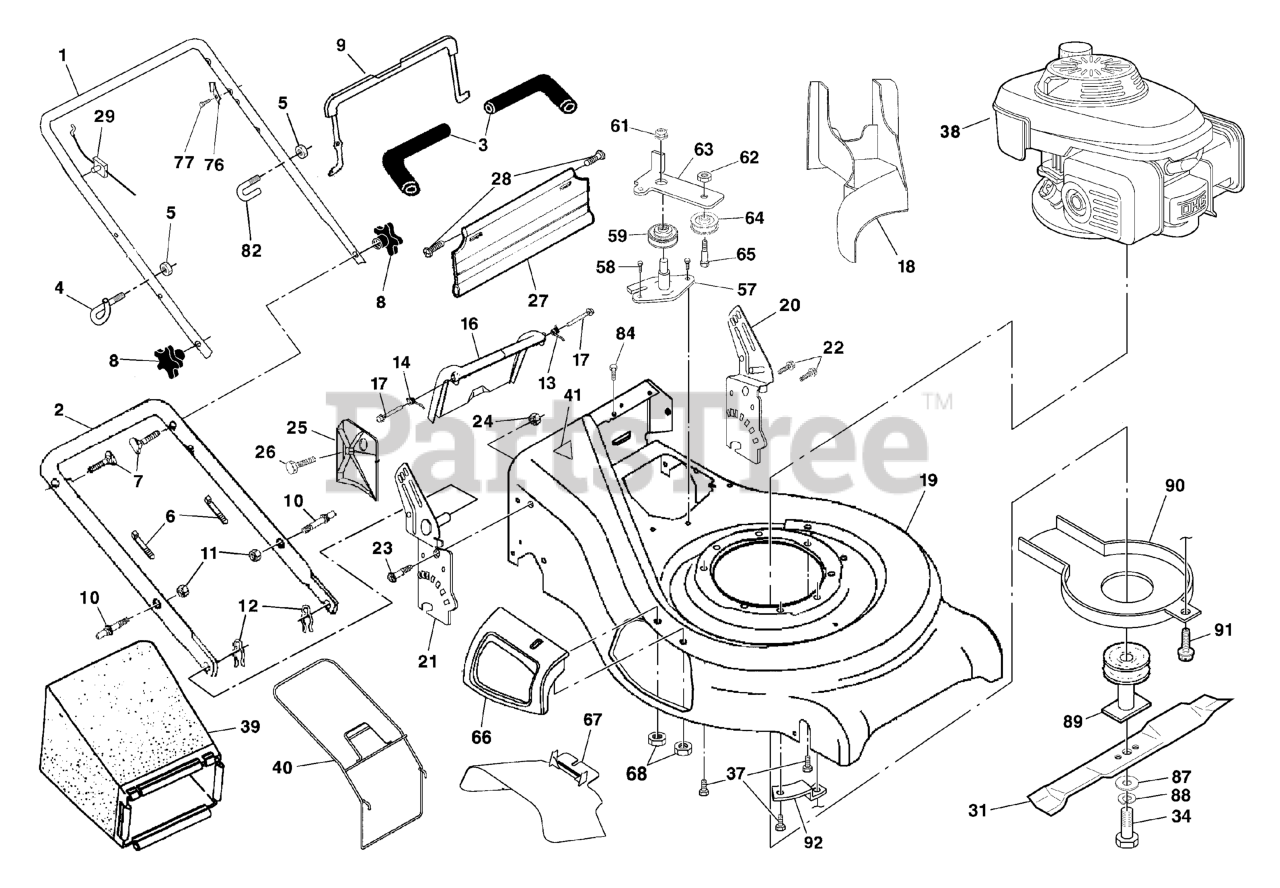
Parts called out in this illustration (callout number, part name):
1	HANDLE.UP.ASM.DSTRT/FLT
2	HANDLE, LOWER
3	GRIP.HANDLE.FOAM.WIDE.(1 SIDE)
4	ROPE, GUIDE
5	NUT
6	TIE GUIDE
7	BOLT, HANDLE 5/16-18X1.75
8	KNOB.HANDLE.STAR.HUSQ.GRAY
9	BAIL, FLAT AUTO WALK
11	NUT.CENTERLOCK.5/16-
12	HAIRPIN COTTER
13	SPRING.RH.REAR.DOOR.21.RWGD
14	SPRING.LH.REAR.DOOR.21.RWGD
16	DOOR.REAR.PLASTIC.21.RWGD.BLAC
18	PLUG, MULCHER
19	RP KIT.HSG.21.RGD.MC.ORAN
20	HANDLE BRACKET ASM. LH
21	HANDLE BRACKET ASM. RH
22	SELF-TAPPING SCREW 5/16-18X3/4
23	BOLT, HEX HEAD 5/16-18
24	NUT.71038.31-18.HEX.NYLOCK
25	CLIPPING DEFLECTOR
27	SKIRT, REAR
28	HINGE SCREW
29	ENGINE ZONE CONTROL CABLE
31	BLADE.21.PUSH/RWGD/FWG
34	SCREW, HEX HD 3/8-24 X 1-3/8
37	BOLT 3/8-16X1-1/8
39	GRASS CATCHER BAG
40	GRASS CATCHER FRAME
41	DECAL HYT
57	BRACKET ASSEMBLY
59	PULLEY ASSY
61	NUT
62	LOCKNUT
63	IDLER ARM
64	IDLER PULLEY
65	SHOULDER BOLT
66	MULCHER DOOR ASM.
67	DEFLECTOR, DISCHARGE
76	BRACKET UPSTOP
87	WASHER,HARDEN
88	LOCKWASHER
89	BLADE ADAPTOR / PULLEY
90	DEBRIS SHEILD
91	SCREW
92	BRACKET
